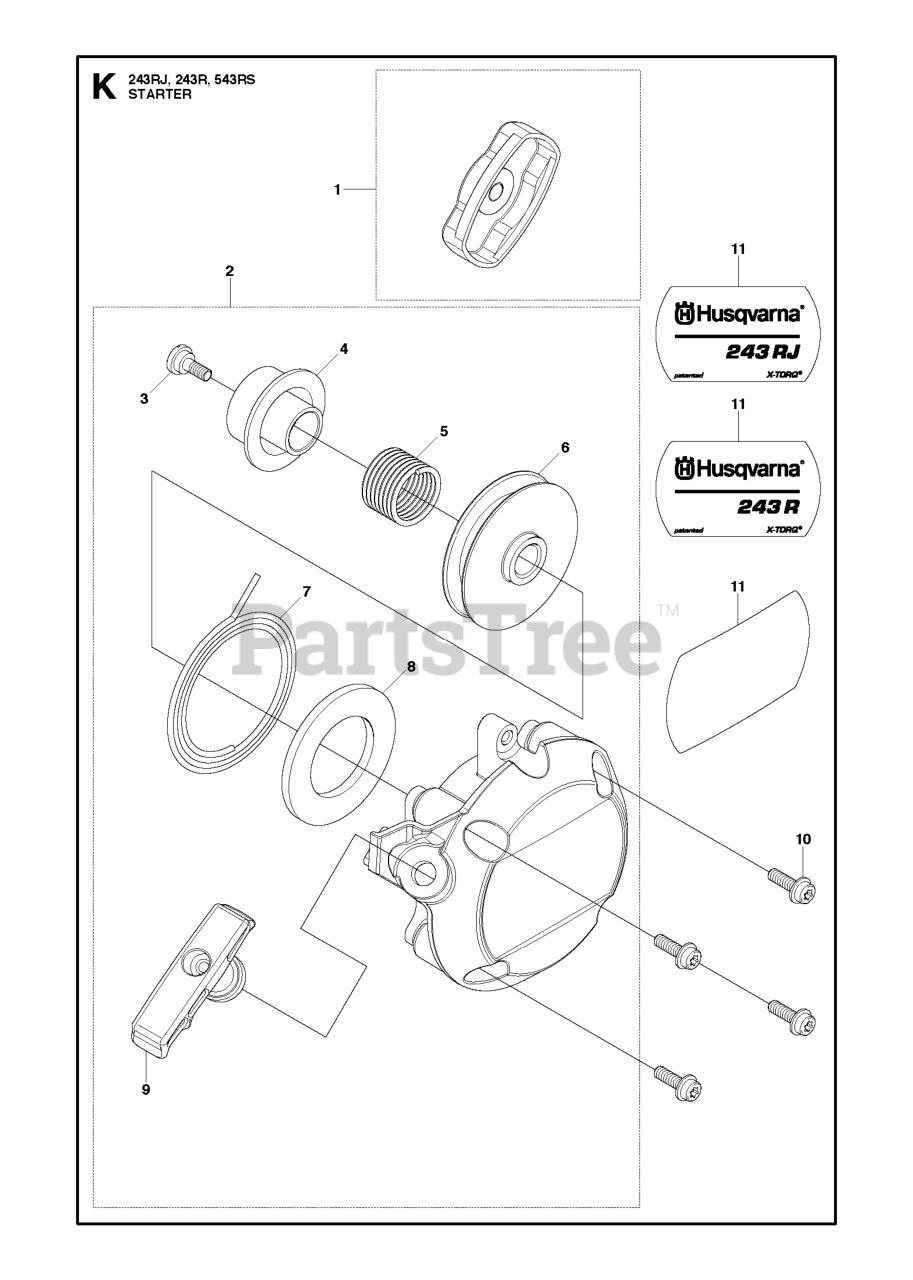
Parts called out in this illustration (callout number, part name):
1	PULLEY ASSY
4	PLATE, CAM
5	SPRING, DAMPER
8	SPRING,SPIRAL
10	BOLT TORX
11	LABEL,RECOIL
11	DECAL RECOIL GZ40N7
